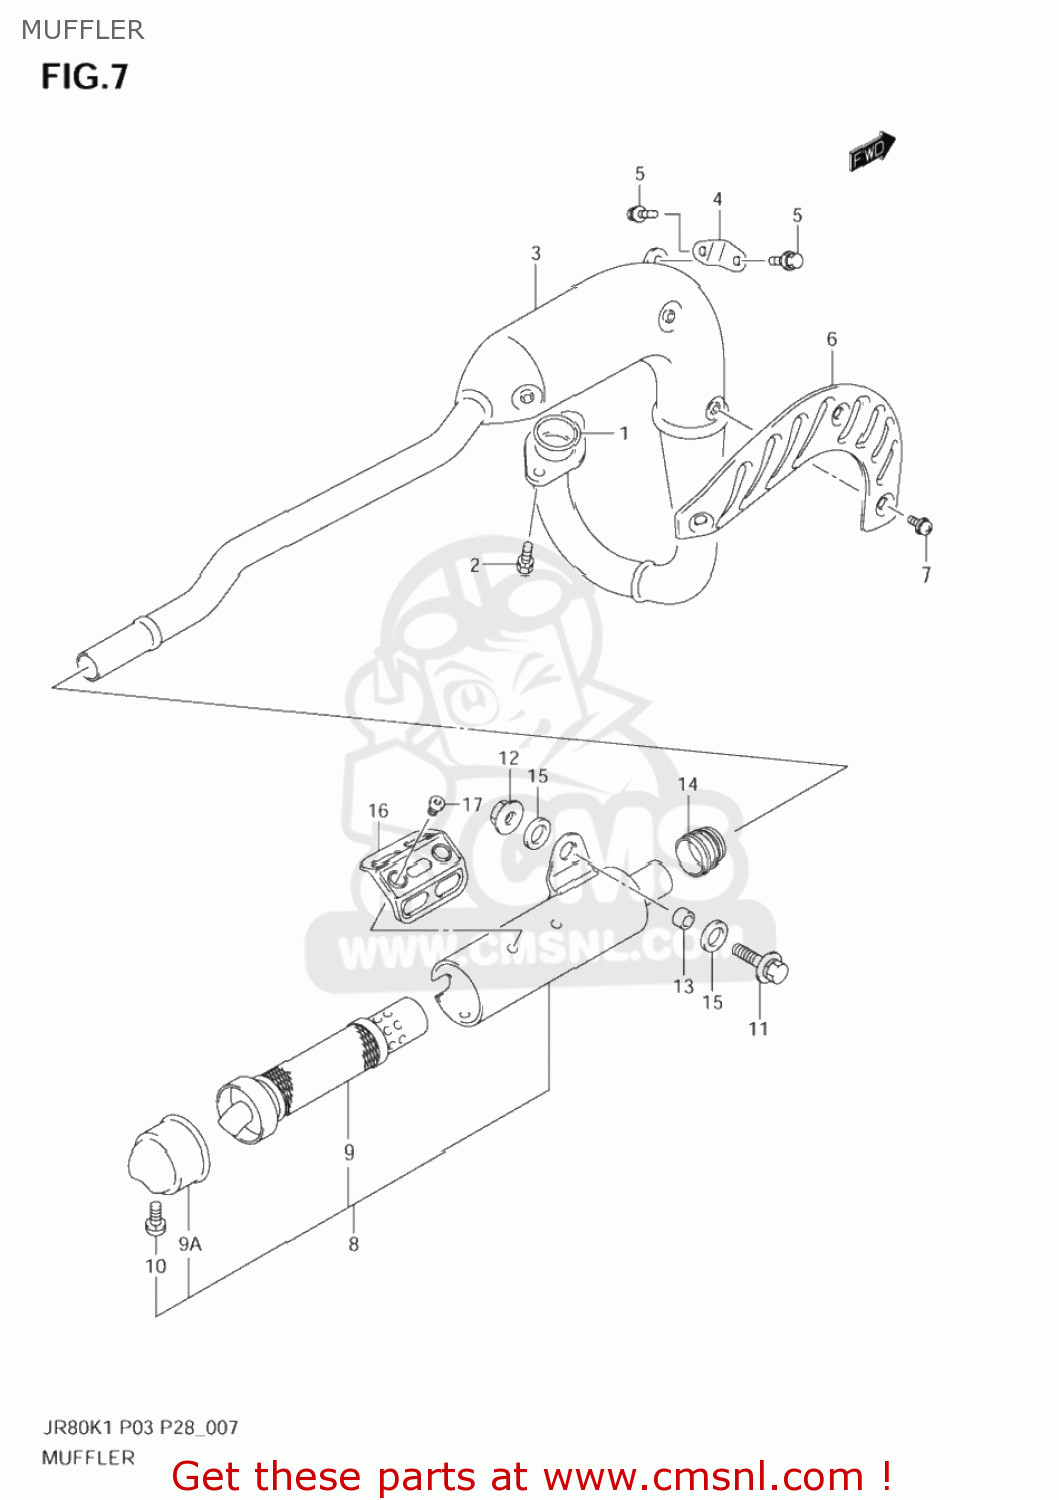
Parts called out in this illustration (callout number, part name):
1	GASKET,EXHAUST (NAS)
2	BOLT
3	BODY,MUFFLER 1ST
4	DAMPER,MUFFLER
5	BOLT
6	COVER,MUFFLER
7	SCREW
8	MUFFLER ASSY,2ND
9	ARRESTER
9A	CUTTER,MUFFLER TAIL
10	BOLT
11	BOLT(8X30)
12	NUT
13	SPACER,8.5X14X9
14	CONNECTOR,MUFFLER
15	CUSHION
16	COVER,2ND MUFFLER
17	SCREW
